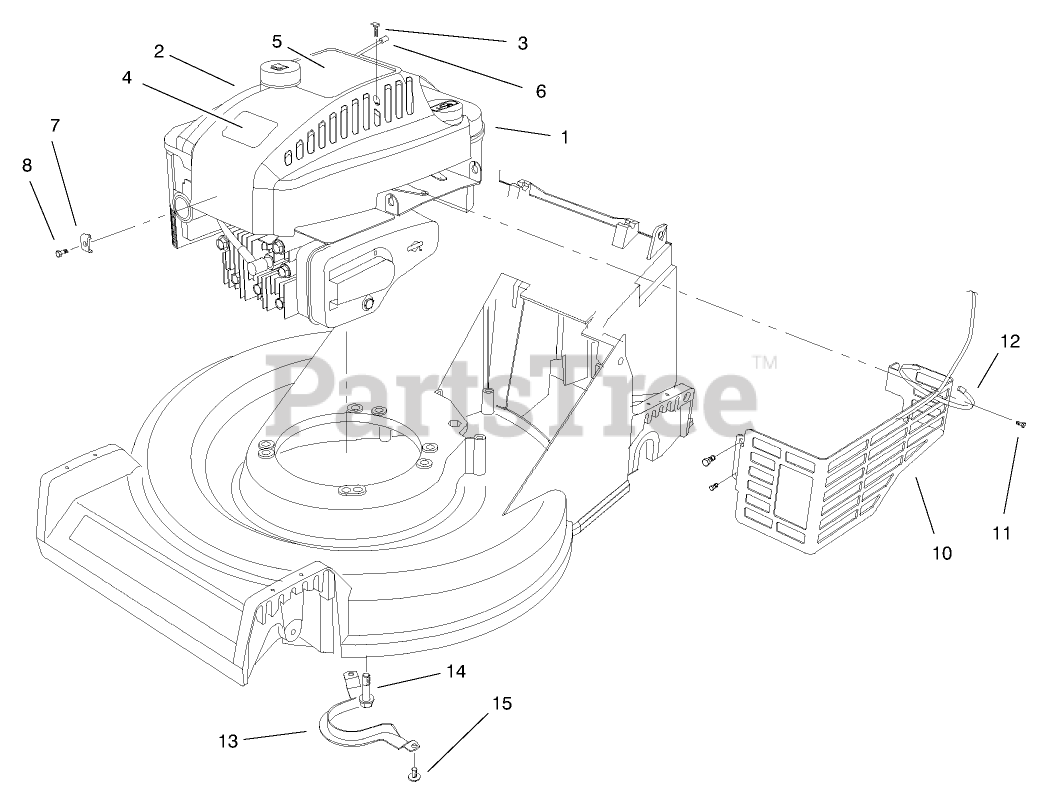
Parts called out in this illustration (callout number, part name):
1	Engine
2	SHROUD-ENGINE
4	DECAL
5	DECAL - RECOIL
6	STOP-ROPE
7	CLAMP-CASING
8	SCREW-CLAMP
12	TIE-CABLE
14	SCREW-HWH
15	SCREW-HWHTF
